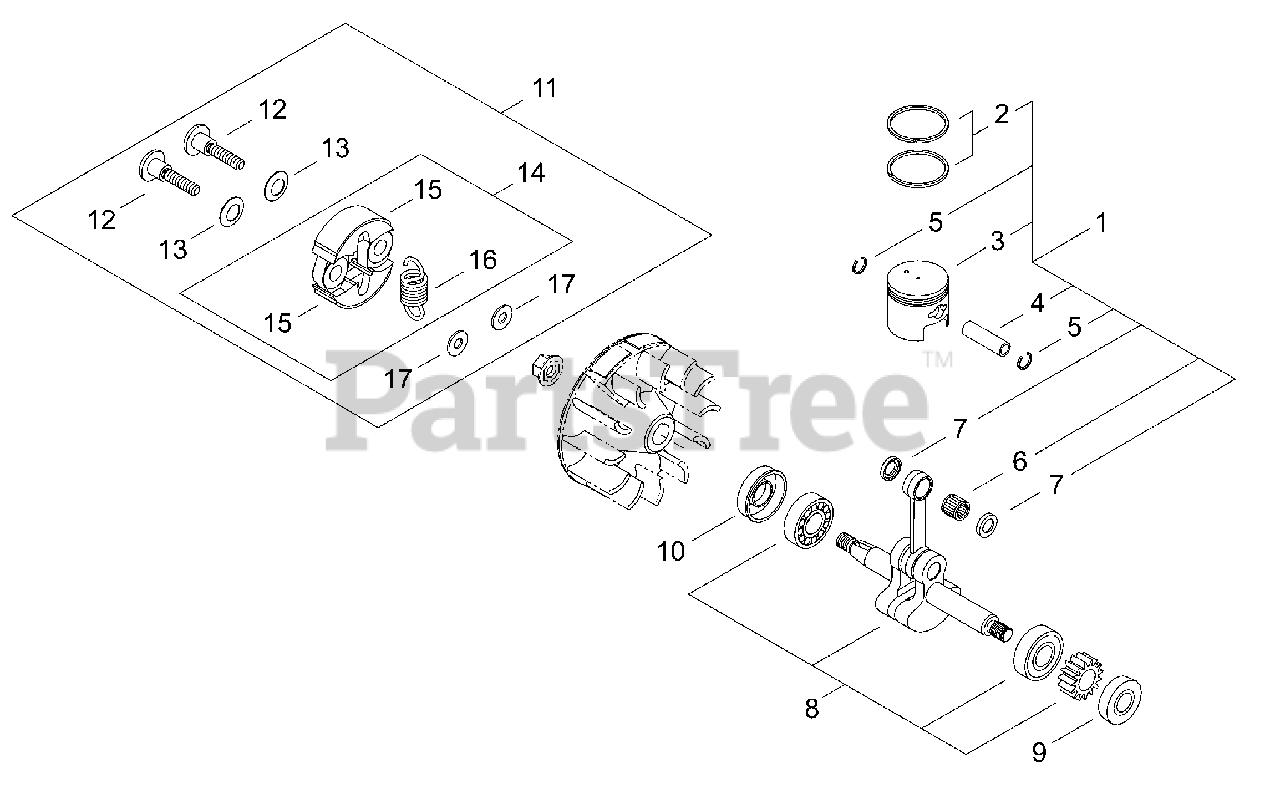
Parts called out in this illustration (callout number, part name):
1	PISTON KIT
2	RING, PISTON
3	PISTON
4	PIN, PISTON
5	RING, RETAINING
6	BEARING, NEEDLE
7	SPACER - 9
8	CRANKSHAFT ASSY
9	SEAL, OIL - 12
10	SEAL, OIL - 12
11	CLUTCH SHOE SET
12	BOLT, CLUTCH
13	WASHER - SPRING
14	CLUTCH ASSY
15	SHOE, CLUTCH
16	SPRING, CLUTCH
17	WASHER - 6
